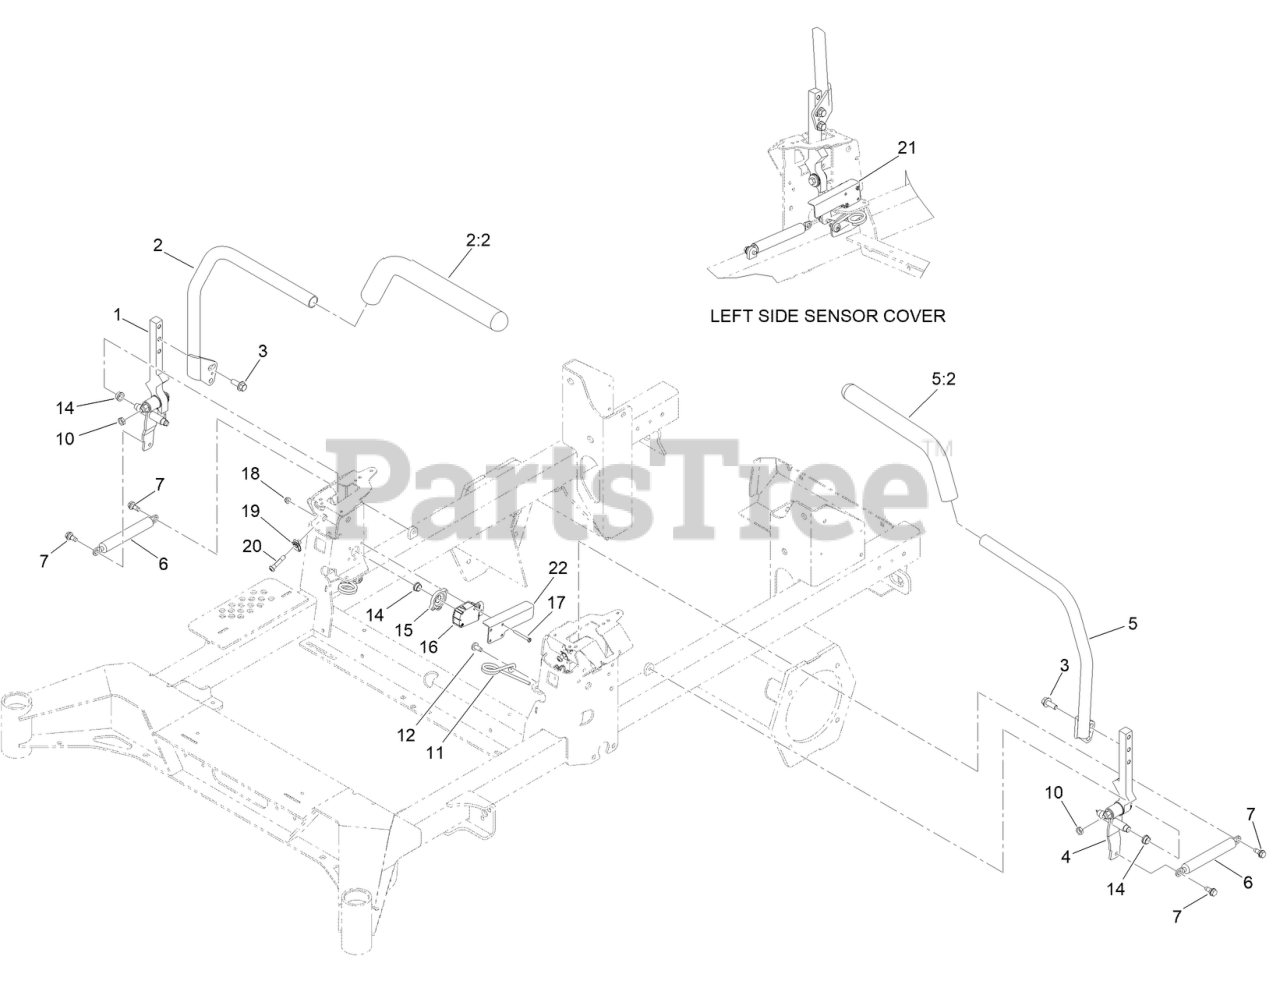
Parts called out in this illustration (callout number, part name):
1	MOTION CONTROL ASM-RH
2	HANDLE ASM - RH
2:2	GRIP-CONTROL, LEVER
3	SCREW-HHF
4	MOTION CONTROL ASM-LH
5	HANDLE ASM - LH
5:2	GRIP-CONTROL, LEVER
6	DAMPER
7	SCREW-SHOULDER
10	NUT-JAM
11	SPRING-TORSION
14	BUSHING-FLANGE
15	SPACER-SENSOR
16	SENSOR-POSITION
17	SCREW-SHH
18	NUT-HEX FLANGE
20	SCREW-HSBH
21	PLATE-COVER, SENSOR LH
22	PLATE-COVER, SENSOR RH
